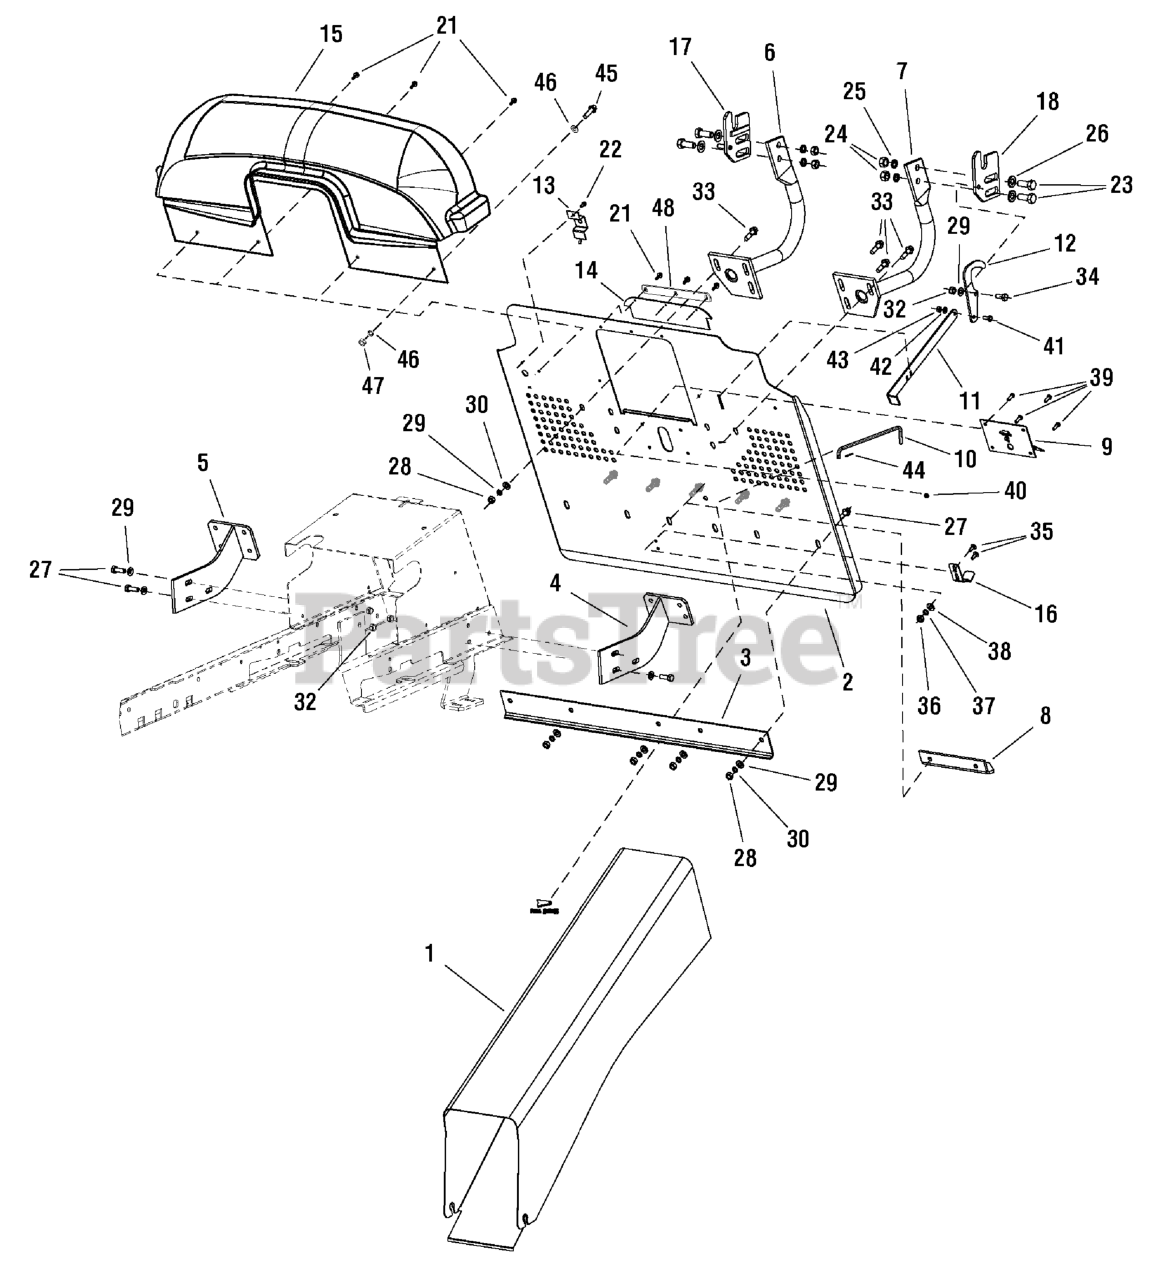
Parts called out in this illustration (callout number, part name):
2	BACK PLATE
4	HOLDER, Back Plate Left
5	HOLDER, Back Plate Right
6	HOLDER, Collector Right
7	HOLDER, Collector, Left
9	SWITCH, Full Collector
10	TIE ROD, Bypass 0-8045-260
11	TIE ROD, Latch
13	COVER, Switch
14	PAD, Rubber
15	TRANSITION PART, Plastic
16	SPRING, Collector, Lock
17	HOLDER, Adjustable, Right
18	HOLDER, Adjustable, Left
21	SCREW, Self Tap, 5.5 x 19
22	SCREW, ST 4.2 x 9.5
23	BOLT, M12 x 30
24	NUT, M12
25	WASHER, 13
26	WASHER, 12
27	BOLT, M8 x 25
29	WASHER, 8.4
30	WASHER, 8
33	BOLT, M8 x 30
34	BOLT, M8 x 20
35	BOLT, M5 x 16
37	WASHER, 5.3
38	WASHER, 5
39	BOLT, M5 x 16
41	BOLT, M6 x 16
42	WASHER, 6.4
44	SPINDLE, 2 x 20
45	BOLT, M4 x 16
46	WASHER, 4.3
48	PAD, Packing
